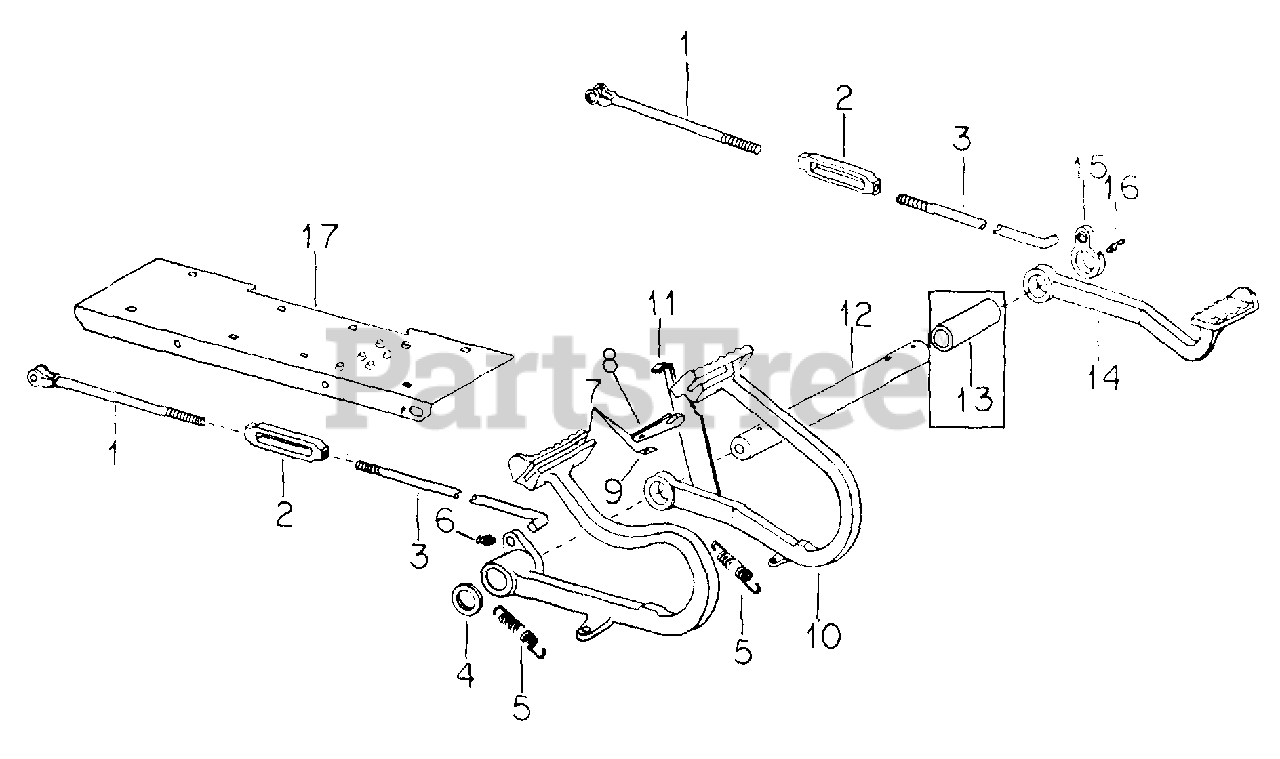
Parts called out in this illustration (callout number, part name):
1	ROD ASSY, BRAKE REAR
2	TURNBUCKLE BRAKE ROD
3	ROD, BRAKE FRONT
4	WASHER, 13/32 X 1-1/2 X .12
5	SPRING, BRAKE RETURN
6	FITTING, 3/16 STR DRIVE TYPE LUB
7	PEDAL ASSY, BRAKE RH
8	PLATE, BRAKE PEDAL LOCK
10	PEDAL ASSY, BRAKE LH
11	STOP, PEDAL RATCHET
12	SHAFT, BRAKE PEDAL
13	BUSHING, CLUTCH PEDAL - PART OF 545419-R91
14	PEDAL, CLUTCH
15	LEVER, BRAKE LH
16	FITTING, 1/8-27 PTF SPECIAL SHORT STR LUBRICATION
17	PLATFORM, ASSY, RH
